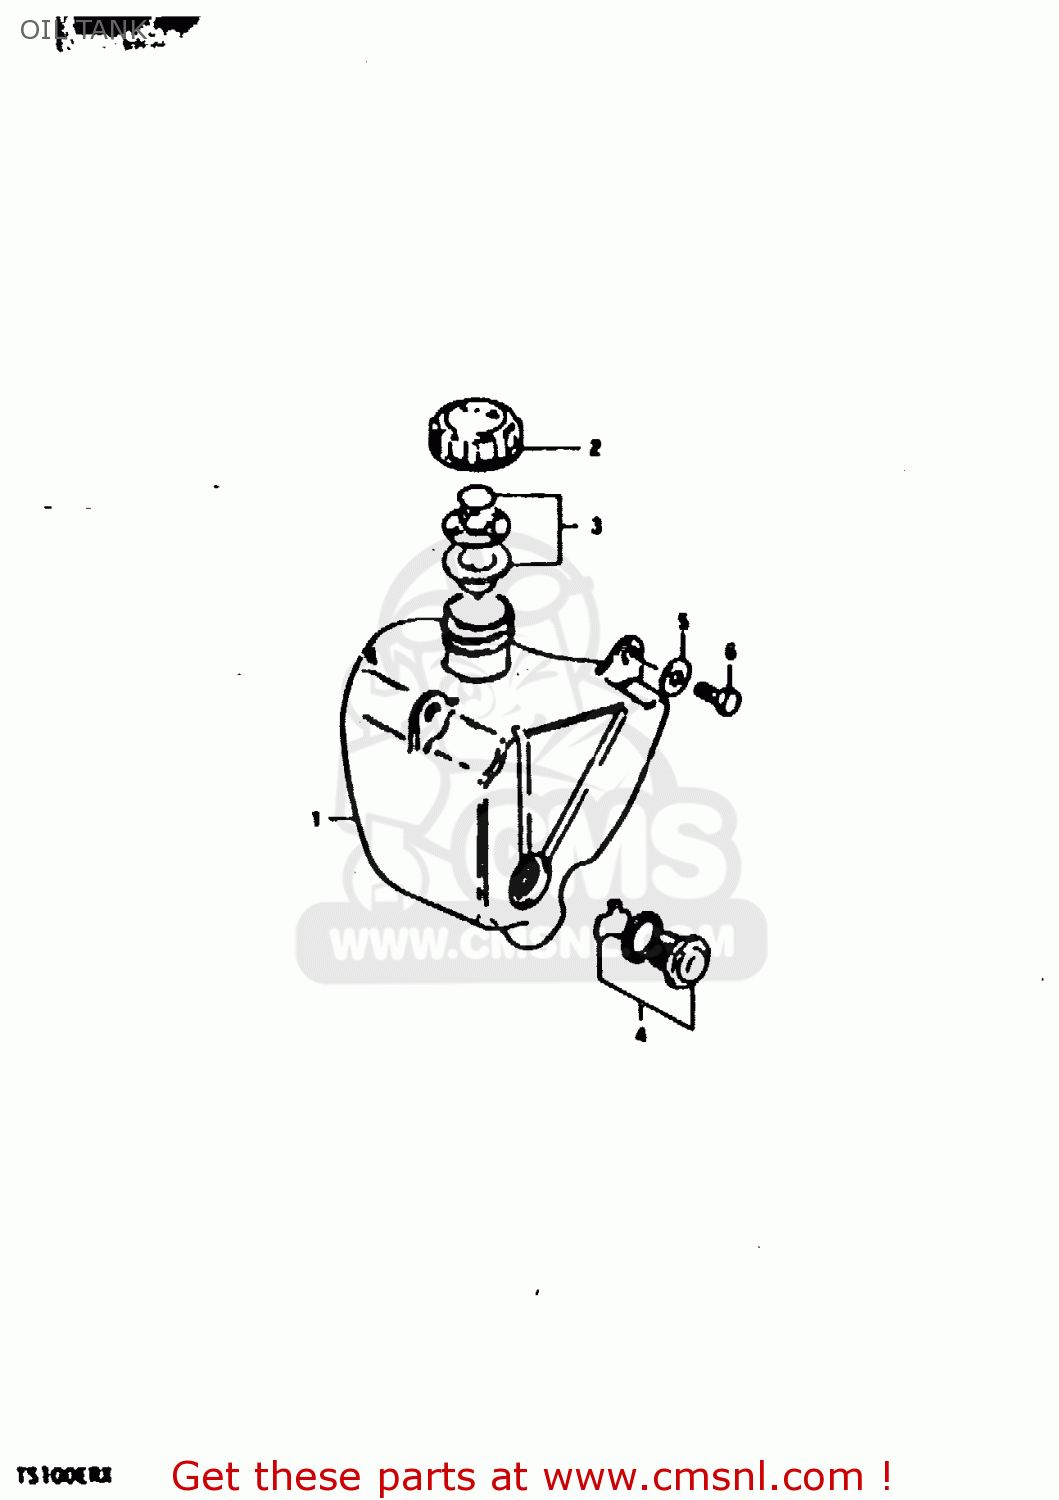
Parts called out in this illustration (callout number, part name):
1	TANK,OIL
2	CAP,OIL TANK
3	GASKET SET (NAS)
4	LENS SET,OIL LEVEL
5	WASHER
6	BOLT, UPPER
